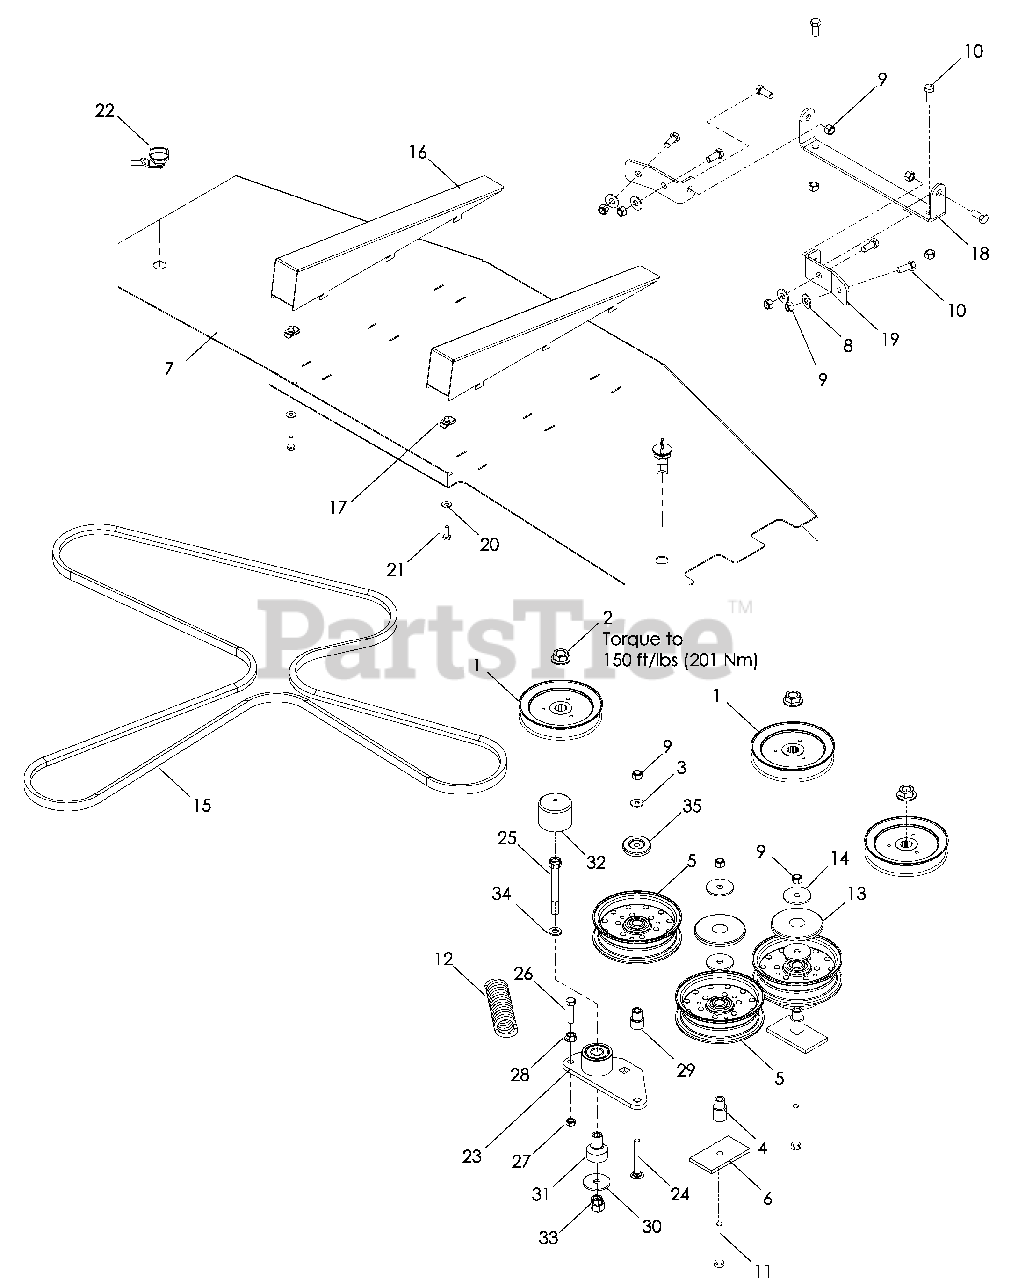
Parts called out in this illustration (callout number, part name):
2	NUT ¾-16 FLANGE
3	WASHER, THICK 3/8
4	BUSHING, IDLER
5	PULLEY, IDLER
6	PAD, PAINTED
7	COVER, BELT, 52
8	WASHER 3/8 FLAT
9	NUT 3/8-16 HEX NYLOC
10	HCS 3/8-16 x 7/8
11	HCS 3/8-16 x 3
13	DUST CAP, TOP
14	WASHER, 3/8 SPECIAL
15	BELT, DECK 52
17	RETAINER ¼-20 "U" TYPE
18	HINGE, BIN
19	BASE, HINGE
20	WASHER, ¼ FLAT SAE
21	HCS ¼-20 x ¾
22	LATCH, SHORT WING
23	ARM, IDLER, W/BEARINGS
24	RHSNB 3/8-16 x 2¾
25	HCS ½-13 x 3¼
26	HCS 3/8-16 x 1½ GR 8
27	NUT 3/8-16 HEX JAM
28	NUT 3/8-16 HEX WHIZLK
29	BUSHING, IDLER
30	WASHER, SUPPORT
31	PIVOT, BEARING
32	CAP, VINYL
33	NUT ½ HEX NYLOC
34	WASHER, BELLEVILLE ½
35	SHIELD, DUST
